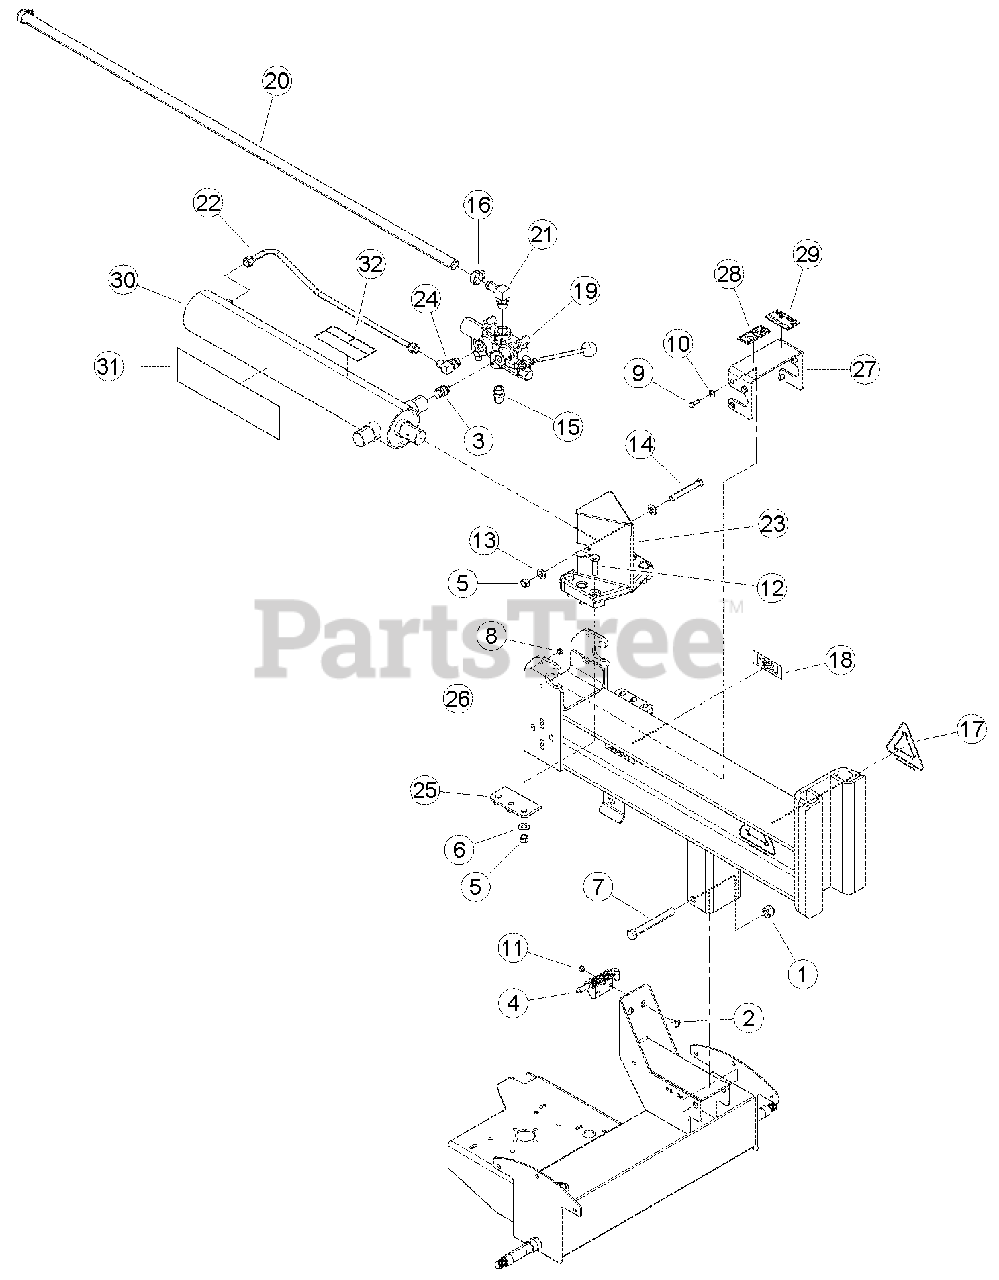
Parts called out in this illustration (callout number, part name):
1	NUT, 5/8-11 UNC NYLOCK
2	BOLT, 5/16-18 X 3/4 CRG GR5 SN
3	ADAPTER, -8 MORING / -8 MORING ADJ
4	LATCH, RH HINGE
5	NUT, 1/2 CENTERLOCK GRB ZP
6	WASHER, 1/2 SAE FLAT ZP
7	BOLT, 5/8 X 5-1/2 HEX HD GR5 ZP
8	NUT 5/16 CENTERLOCK NC ZP
9	BOLT, 5/16 X 1 HEX HD GR5 NC ZP
10	WASHER, 5/16 FLAT ZP
11	NUT, 5/16 NE NYLOCK ZP
12	BOLT, 1/2 X 1-3/4 HEX HD GR5 NC ZP
13	WASHER, 1/2 HI-STRENGTH SAE ZP
14	BOLT, 1/2 X 3-3/4 HEX HD GR8 NC
15	ADAPTER, -10 MORING / -10 MJIC
16	CLAMP, 1-1/4" HOSE
17	DECAL, RECLAIM IT
18	DECAL, MODEL LS21
19	VALVE, LOG SPLITTER
20	HOSE, 0.75 ID X 60" 100R4 HYD
21	ADAPTER, -10 MORING/.75 90 DEG. HOSE
22	TUBE, HYDRAULIC
23	WEDGE, CAST (WAS 36333-12, FOR SERVICE ORDER KIT #77380-00, CAST WEDGE WITH SPACERS)
24	ADAPTER, -8 MORING / -8 MJIC 90 DEG.
25	PLATE, CAST WEDGE BOTTOM
26	WELDMENT, BEAM
27	CHANNEL, CRADLE CYLINDER, SERVICE PART
28	DECAL, CRUSHING ISO
29	DECAL, CYLINDER OPERATION (ISO)
30	CYLINDER, WELDED 4.00 X 24.00, SERVICE PART
31	DECAL, ECHO BEARCAT 14.12 X 4.00
32	DECAL, MUTILINGUAL MANUAL
